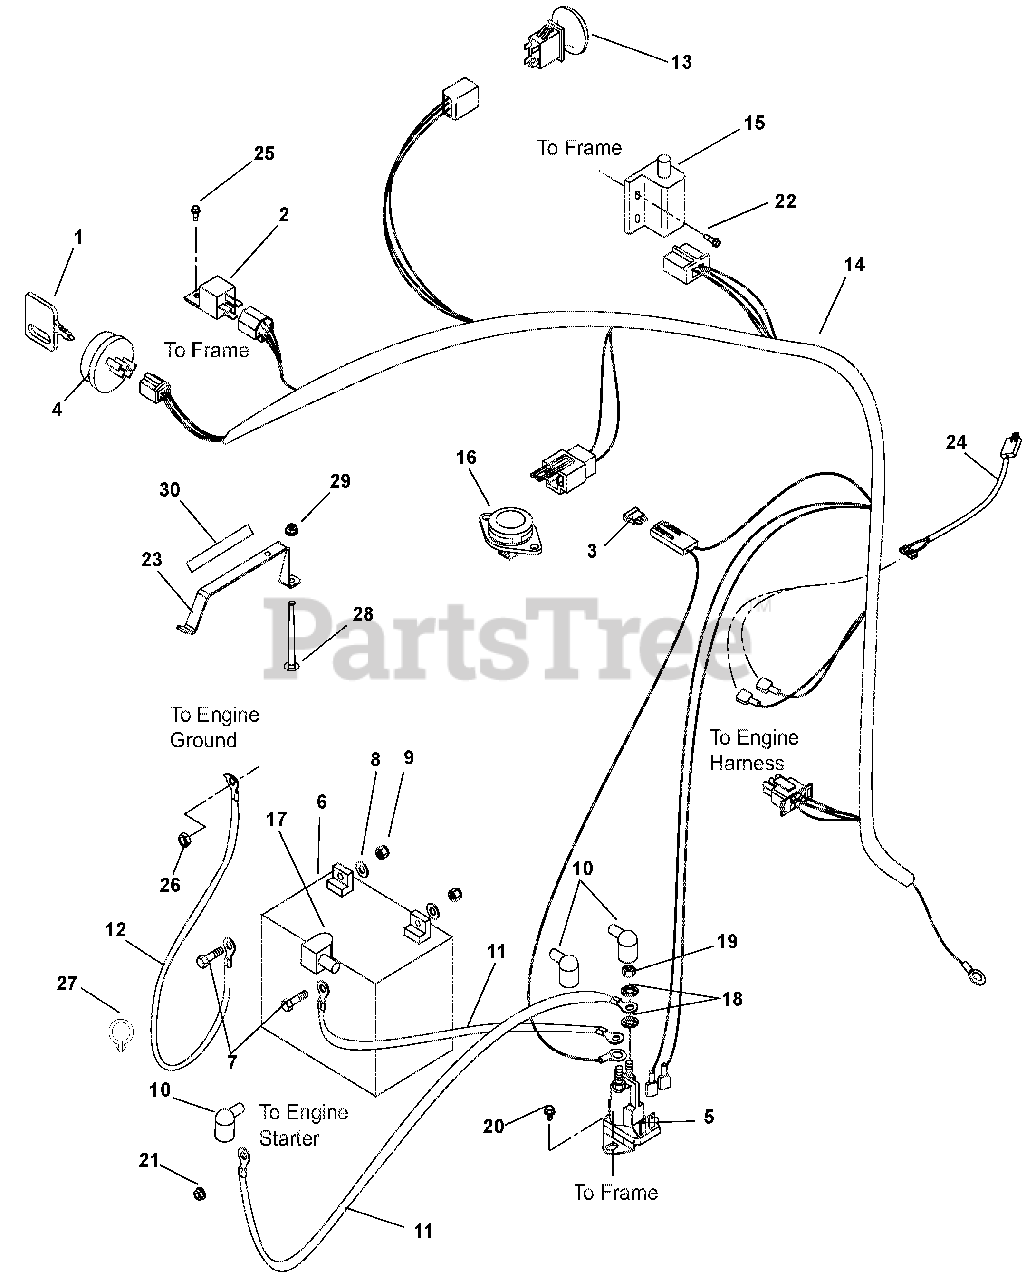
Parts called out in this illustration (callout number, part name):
1	KEY, 03290500 KEYSWITCH
2	RELAY
3	FUSE-25 AMP ATC TYPE
4	KEYSWITCH-IGNITION 3 POS
5	SOLENOID, HP RTV
6	BATTERY, 12V 20HR;190CCA GEP
7	@BLT-HEX .25-20X.75 GR5 YWZC
8	@WSHR-FL-STL.281X.62X.065 YWZC
9	NUT-KEPS .250-20
10	BOOT, EYELET TERMINAL
11	CABLE, POSITIVE 15.00" 6 GA.
12	CABLE, NEGATIVE 26" 6 GA.
13	SWITCH, CLUTCH (YELLOW)
14	HARNESS-WIRING, BBZ
15	SWITCH- DOUBLE POLE N.O./N.O.
16	SWITCH- SEAT
17	INSULATOR
18	WSHR-LOCK INT .31 YWZC
19	NUT-JAM .31-24 YWZC
20	@SCR-TAP .25-20X.37 HWH YWZ TR
21	@NUT-LK-TOP-FLG .25-20 YWZC
22	SCR- 12-14X.75 HX W/HD TEK ZC
23	HOLDDOWN, BATTERY, U1&190CCA
24	HARNESS, CLUTCH
25	@SCR-TAP 12-24X.50 HWH TR YWZC
26	@NUT-LK-CTR-JAM .375-16 YWZC
27	WIRE CLIP
28	@BLT-RDHDSQNK .25-20X4.50 G2YZ
29	@NUT-LK-NYL-FLG .25-20 YWZC
30	DECAL, U1 BATTERY REPLACEMENT
